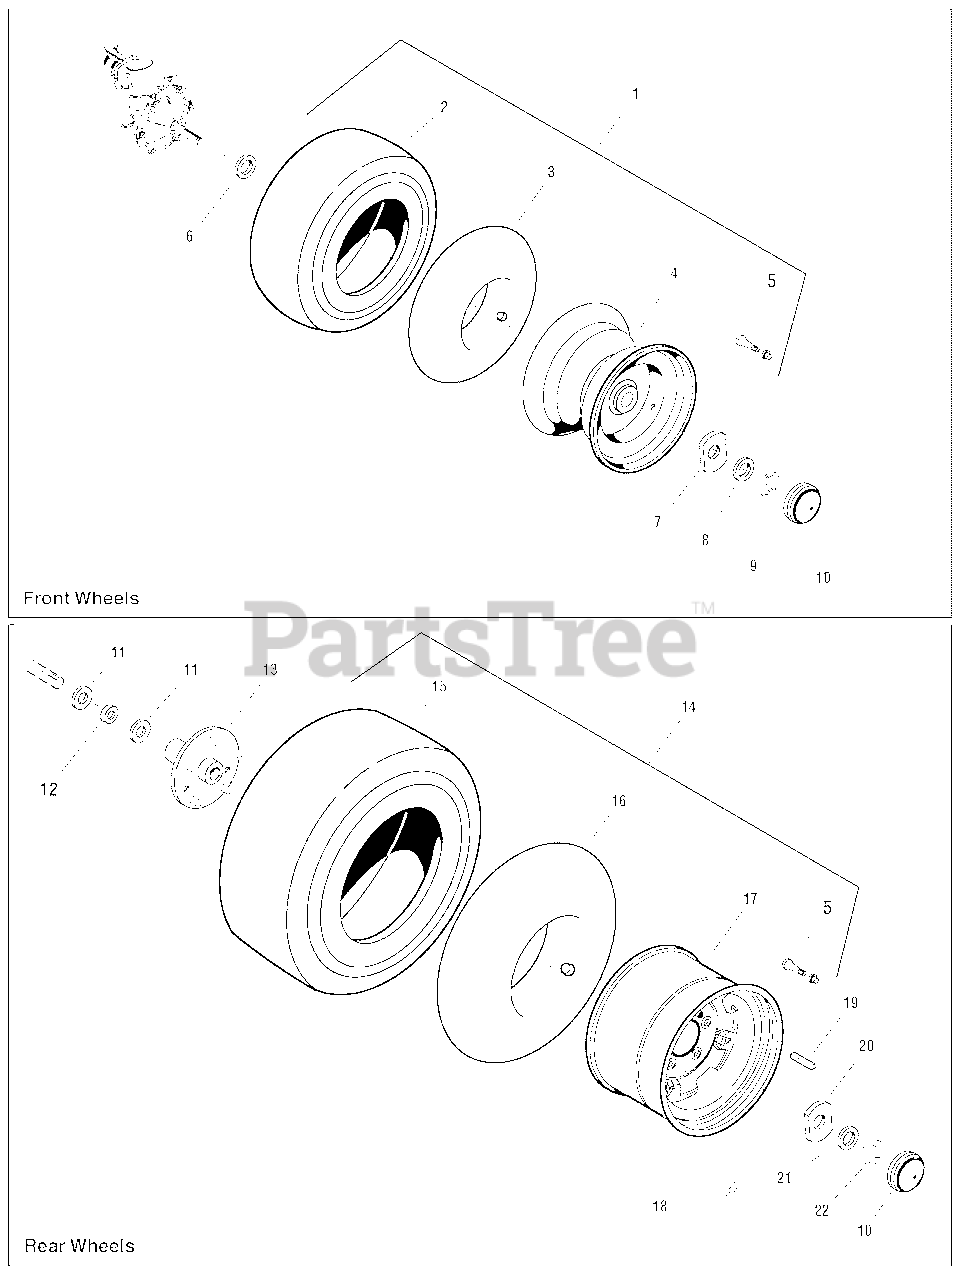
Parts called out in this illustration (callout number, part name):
1	WHEEL & TIRE ASSEMBLY, 16X6.5-8, Front
2	TIRE, 16X6.5-8
3	TUBE, Tire
4	RIM, Wheel Assembly
5	VALVE STEM & CAP ASSEMBLY
6	WASHER, Flat 3/4 x 1-5/8 x 1/8
7	WASHER, Flat
8	WASHER, 3/4
9	RING
10	CAP, Hub
11	WASHER, 1 x 2-1/4 x 1/8
12	SPACER
13	PLATE & HUB ASSEMBLY
14	WHEEL & TIRE ASSEMBLY, 23X10.5-12, Rear
15	TIRE, 23X10.5-12
16	TUBE, Tire
17	WHEEL
18	NUT, Hex, 7/16-20
19	KEY, Hi-Pro 1/4 x 2
20	WASHER, Flat
21	WASHER, Flat
22	RING
